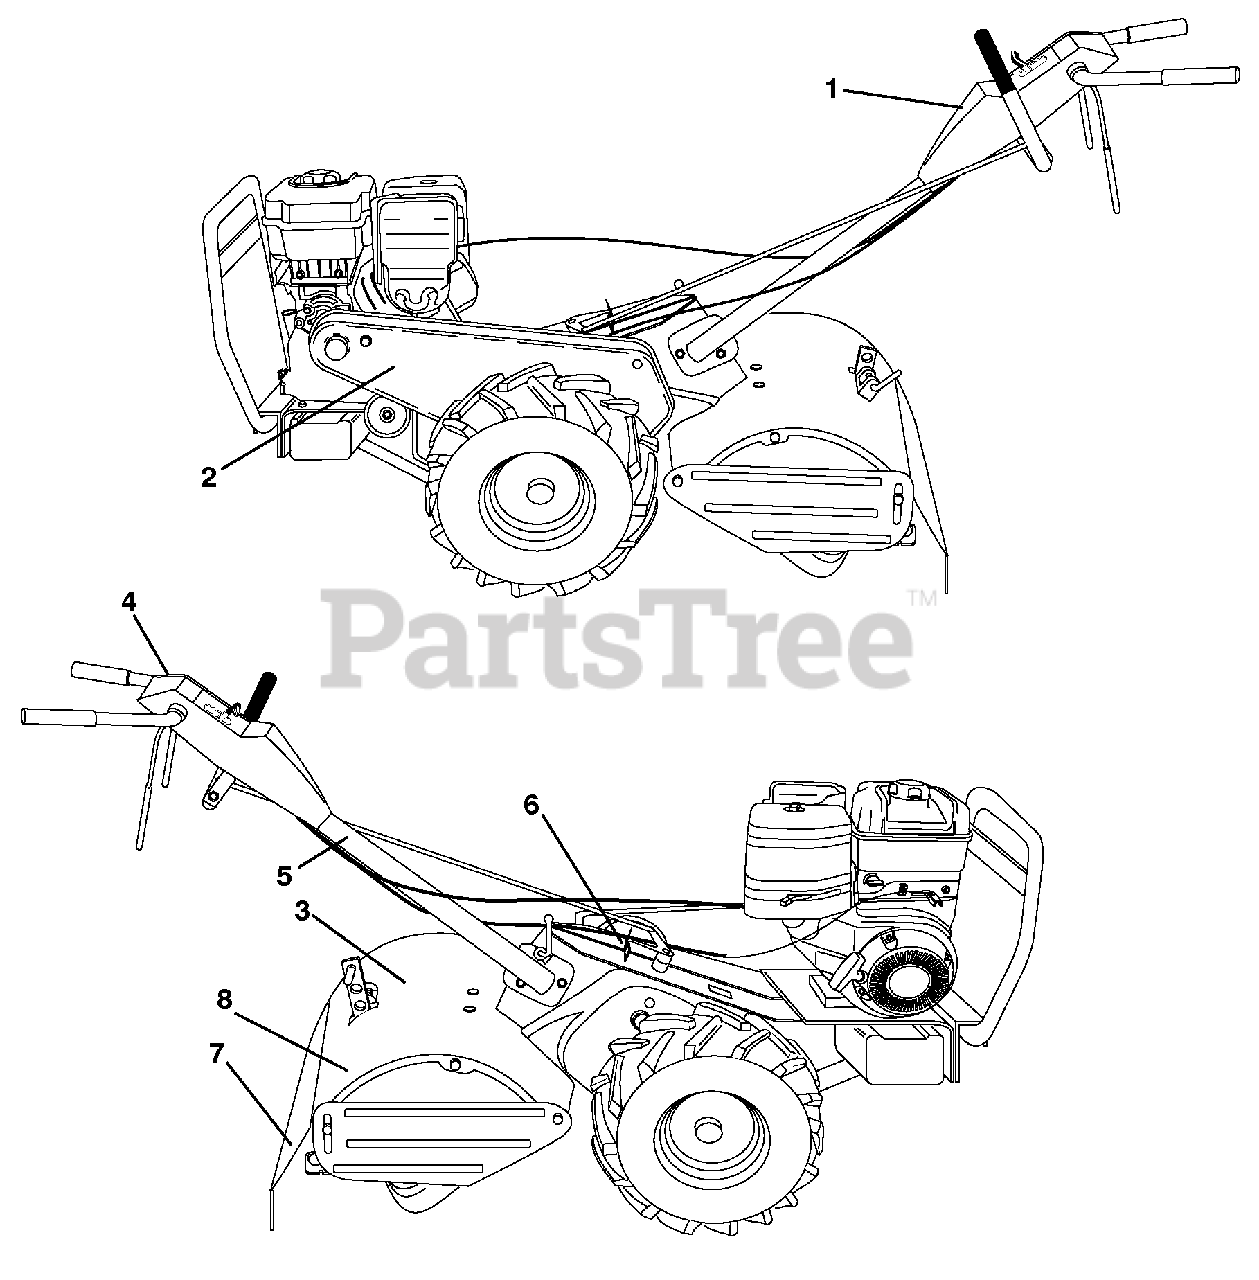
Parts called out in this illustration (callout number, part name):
1	Decal, Logo
2	Decal, Logo
3	Decal, Tine Shield
4	Decal, Instruction, Tilling
5	Decal, Hand Placement
6	Decal, Shift Indicator
7	Decal, Warning,
8	Decal, Warning Shield
